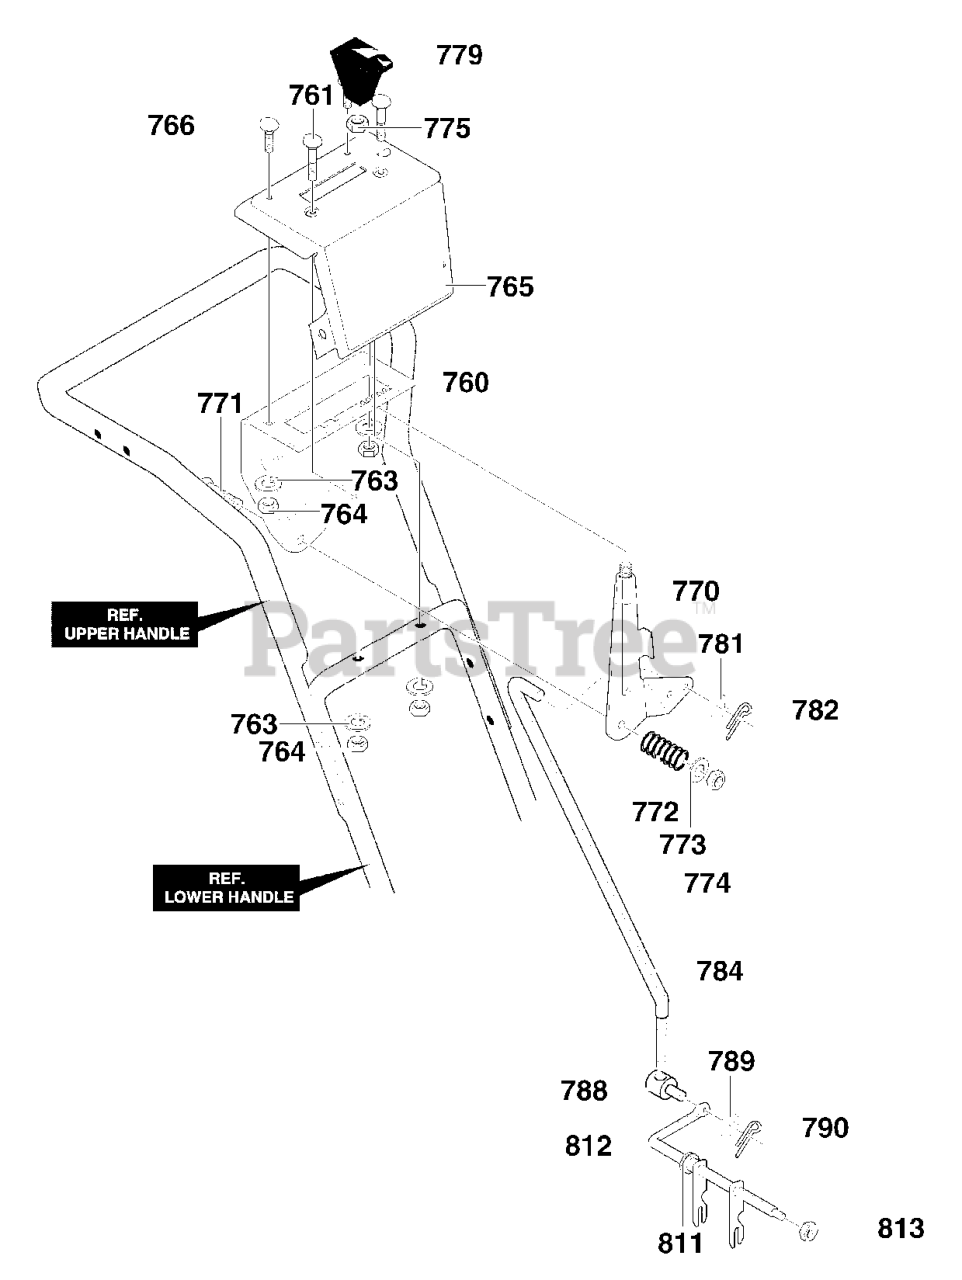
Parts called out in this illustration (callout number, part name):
760	BRACKET, SHIFT CONTROL
761	CARR. BOLT, 1/4-20X.63
764	NUT, 1/4-20
765	CONTROL PANEL
766	CARR. BOLT, 1/4-20X2.00
770	SHIFT LEVER ASSY
771	SCREW, 5/16-18 x 1.75
772	SPRING
773	WASHER, FLAT
774	NUT, 5/16-18 HEXNYL
775	NUT, 3/8-16 HEXJAM
779	KNOB, SHIFT
781	WASHER, FLAT
782	PIN, COTTER
784	ROD, SPEED CONTROL
788	NUT, TRUNNION 5/16-24
789	WASHER, FLAT
790	PIN, COTTER
811	FLANGED BEARING
812	ROD ASSY, YOKE PANEL
813	NUT, 3/8-16 HEX
